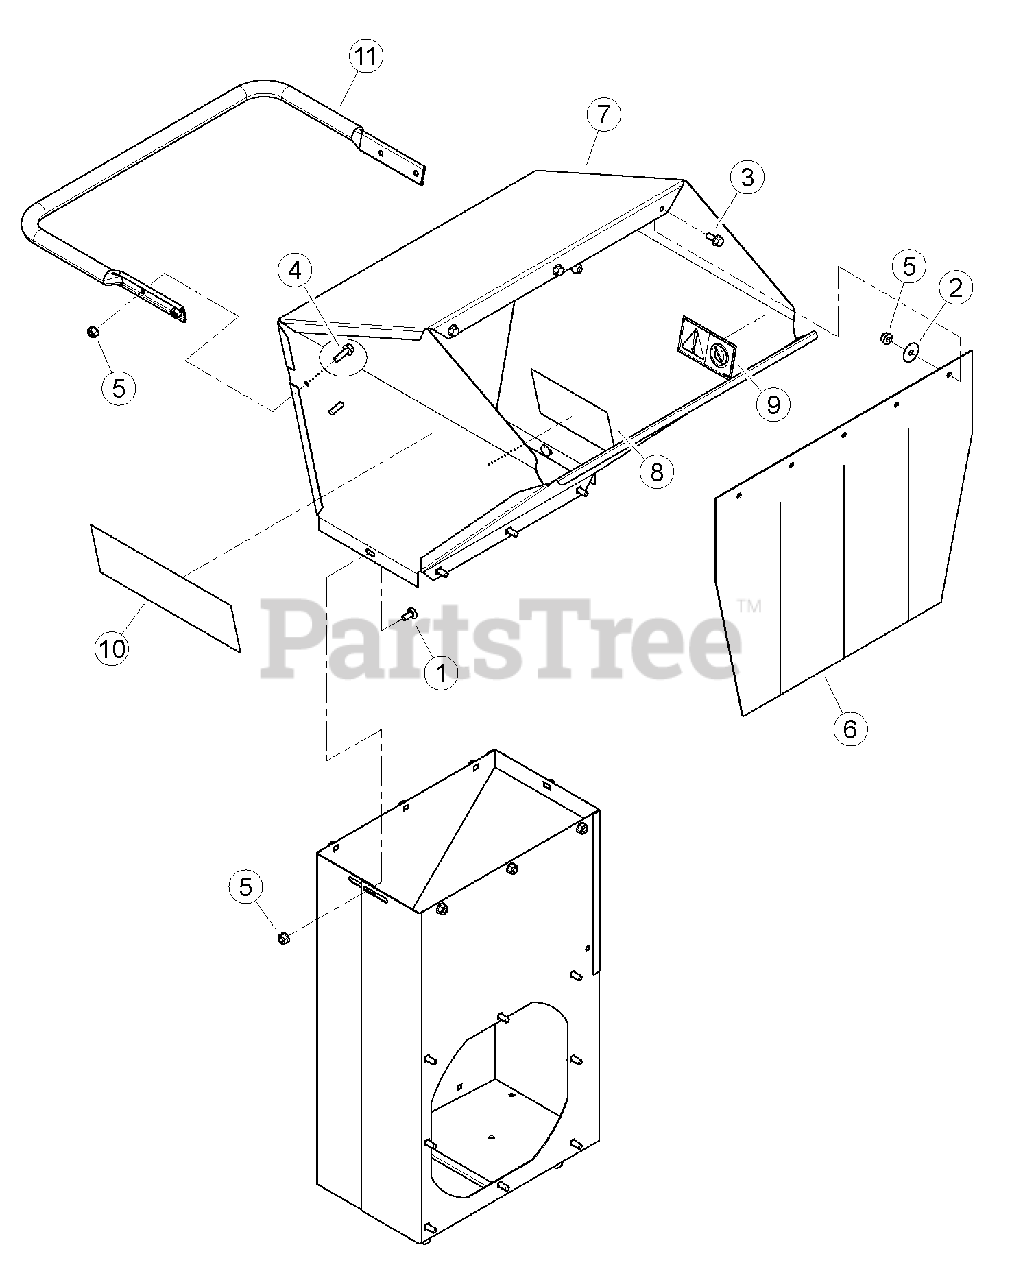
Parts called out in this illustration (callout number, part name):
1	BOLT, 5/16-18 X 3/4 SN GR5 CRG
2	WASHER, 5/16" FENDER ZP
3	BOLT, 5/16 X 3/4 FLANGE NC
4	BOLT, 5/16 X 1 FLANGE NC
5	NUT, 5/16-18 NYLOCK FLANGE
6	BELTING, RENTAL HOPPER
7	ASSEMBLY, WIDE BODY RENTAL HOPPER W/ DECALS
8	DECAL, BLADE DANGER ISO
9	DECAL, SHREDDER SIZE ISO
10	DECAL, ECHO BEARCAT 12.00 X 4.00
11	HANDLE, RENTAL HOPPER
